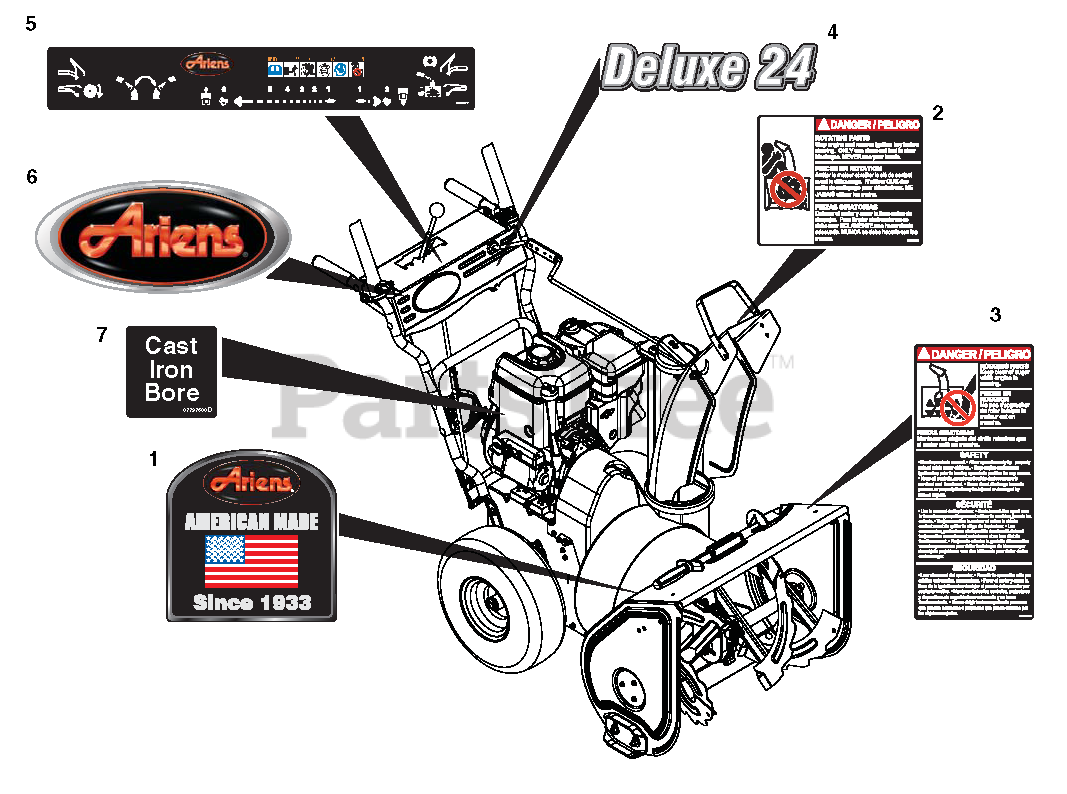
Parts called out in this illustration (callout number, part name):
1	DECAL, ARIENS SINCE 1933
2	DECAL, DANGER - ROT. PARTS
3	DECAL, DANGER
4	DECAL,ST24 DELUXE-COMPACT DASH
5	DECAL, CONTROL, COMPACT/DELUXE
5	DECAL, CONTROL TRACK W/SM DASH
6	DECAL, ARIENS JEWEL
7	DECAL - CAST IRON BORE
